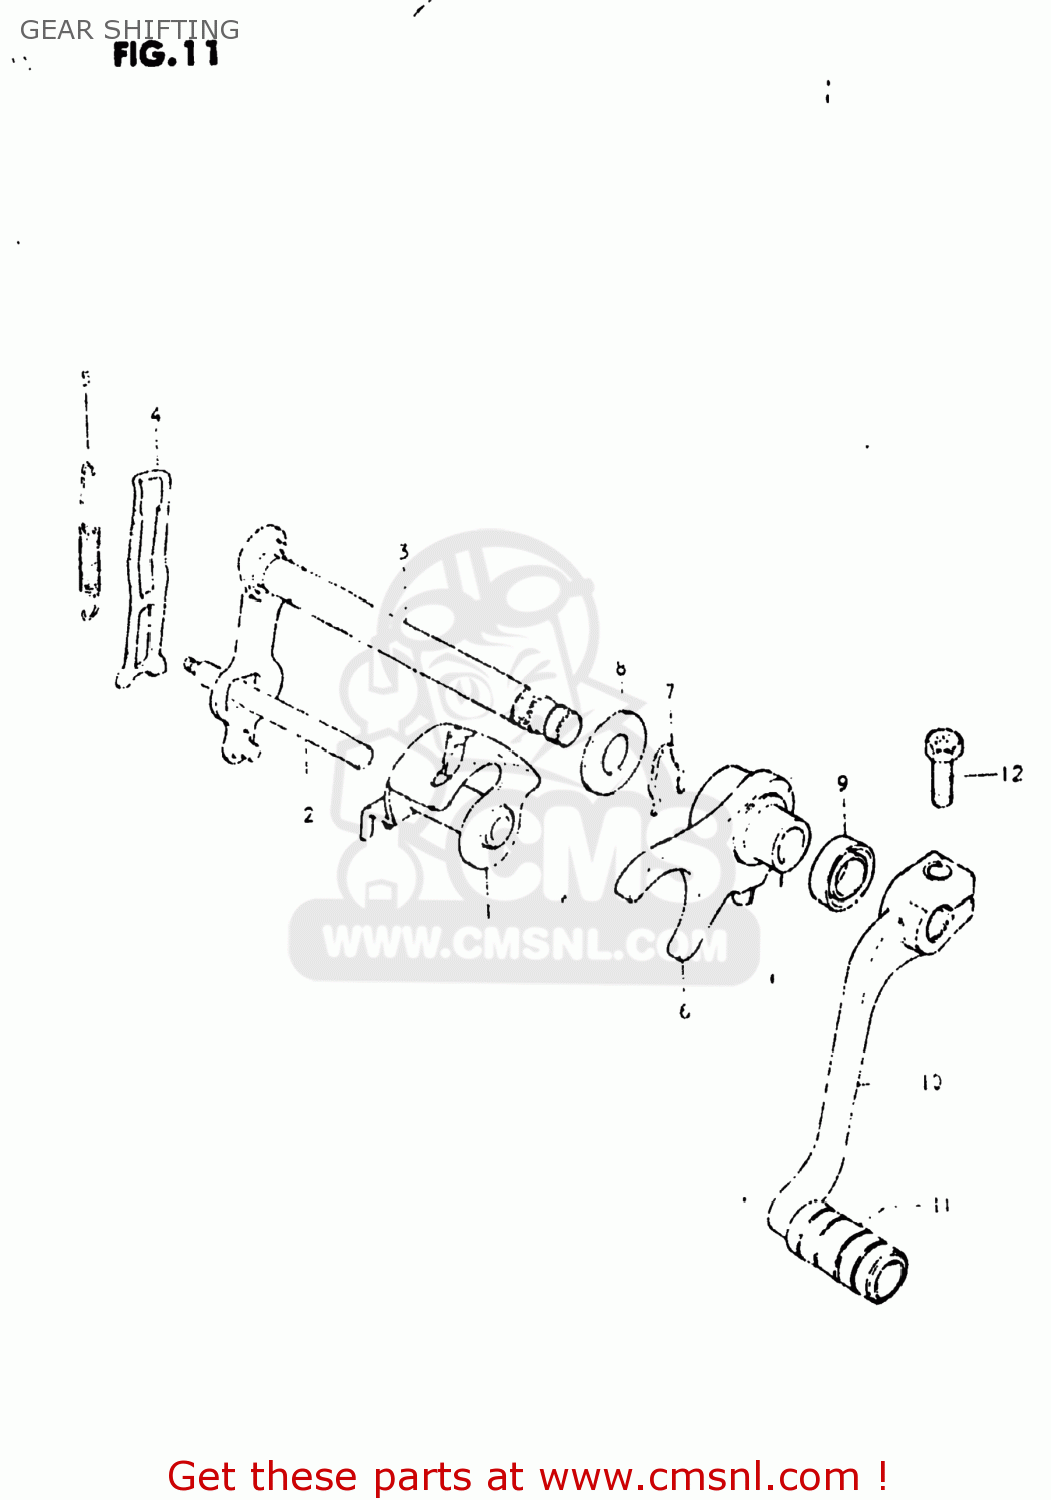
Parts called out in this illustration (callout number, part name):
1	CAM,GEAR SHIFT
2	SHAFT,GEAR SHIFT CAM
3	SHAFT,GEAR SHIFT
4	ARM,GEAR SHIFT CAM STOPPER
5	SPRING
6	FORK,GEAR SHIFT NO.1
7	SPRING,RETAINER
8	WASHER
9	OIL SEAL
10	LEVER ASSY,GEAR SHIFT
11	RUBBER,GEAR SHIFT PEDAL
12	BOLT
